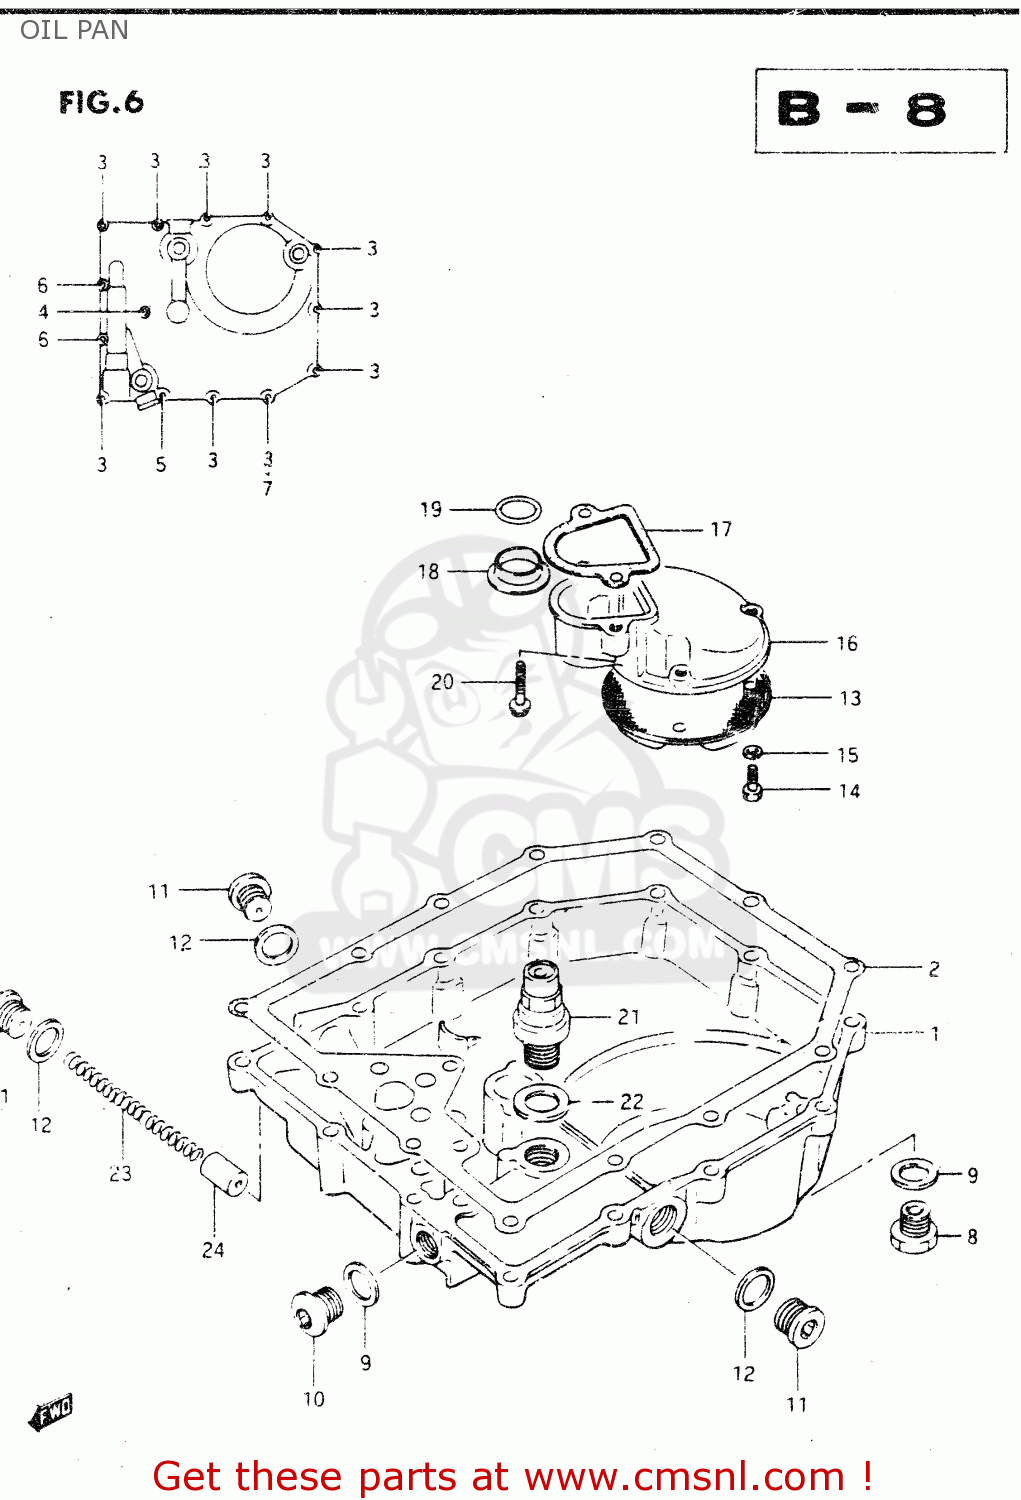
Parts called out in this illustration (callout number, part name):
1	PAN,OIL
2	GASKET,OIL PAN (NAS)
3	BOLT
4	BOLT
5	BOLT
6	BOLT
7	GASKET(5.8X13X1.2) (NAS)
8	PLUG
9	GASKET(14X19.2X2) (NAS)
10	PLUG
11	PLUG
12	GASKET(16X22X2) (NAS)
13	STRAINER,ENGINE OIL
14	BOLT
15	WASHER,LOCK
16	PROTECTOR,OIL STRAINER
17	GASKET,OIL STRAINER PROTECTOR (NAS)
18	GASKET,OIL OUTLET (NAS)
19	O RING(D:3.2,ID:17.8)
20	BOLT
21	VALVE ASSEMBLY,OIL RELIEF
22	GASKET(16X22X2) (NAS)
23	SPRING
24	PLUNGER,OIL CONTROLL
